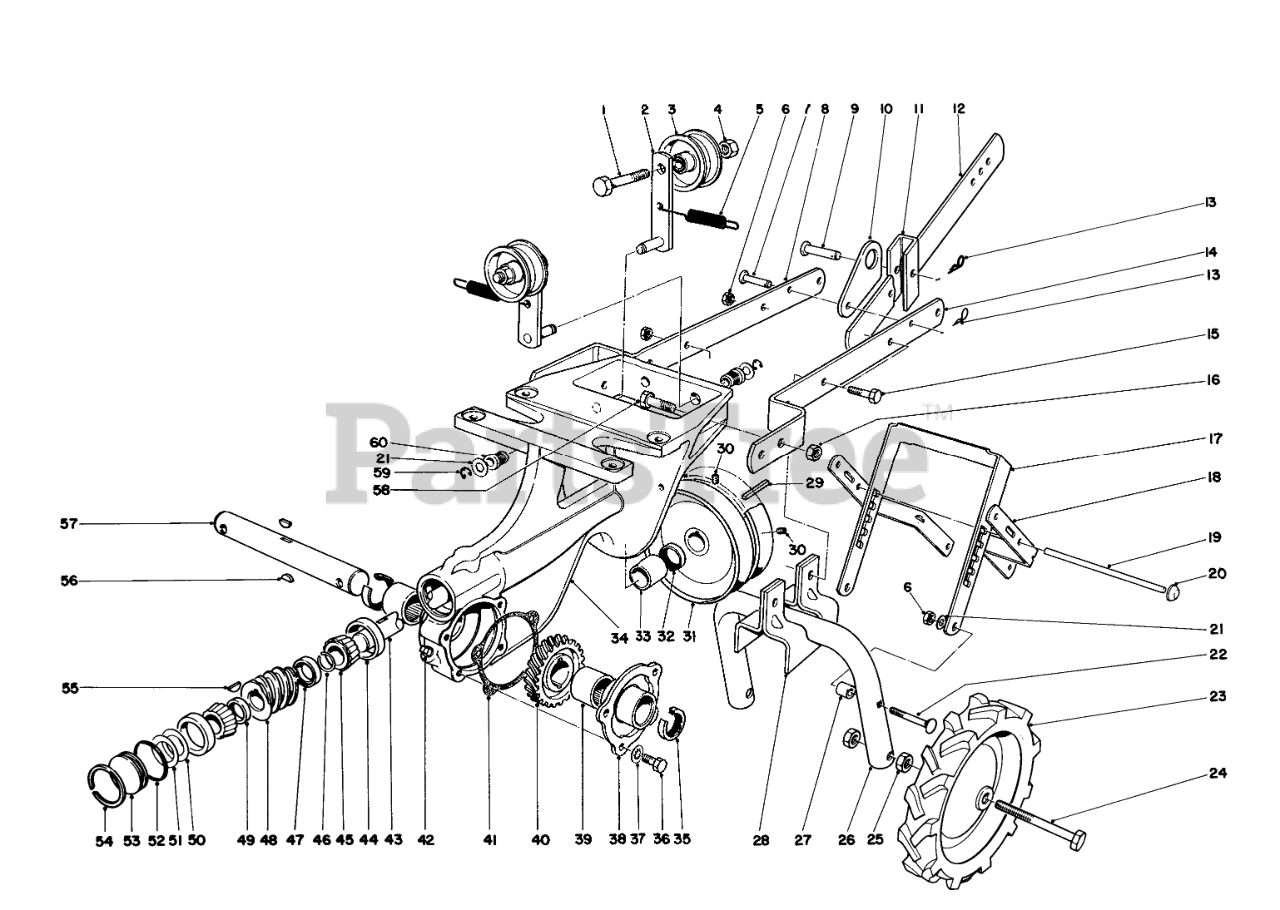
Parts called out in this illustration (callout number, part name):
1	SCREW-HH
2	Idler Arm
3	PULLEY IDLER
4	NUT-LOCK, CONE
5	TENSION SPRING
6	NUT-LOCK, CONE
7	PIN-CLEVIS
8	Drawbar R.H.
9	CLEVIS
10	Latch-Depth Gauge
11	DEPTH GUAGE BRKT
12	Depth Gauge
13	PIN-COTTER
14	Drawbar L.H.
15	SCREW-HH
16	NUT-KEPS
17	Lever Wheel Adjustment
18	HANDLE SUPPORT
19	Shaft-Wheel Adjustment
20	PUSH ON
21	WASHER-PLAIN
22	BOLT-CARR
23	Wheel
24	Wheel Bolt
25	NUT-HEX
26	Axle Yoke
27	Spacer
28	Saddle Yoke
29	KEY-SQUARE
30	SCREW-SET
31	WORM SHAFT PULLEY
32	SEAL-OIL
33	BUSHING
34	Chassis
35	SEAL-OIL
36	1/4-20 X 5/8 CAPSCREW
37	WASHER-LOCK
38	Cover
39	Needle Bearing
40	WORM WHEEL
41	GASKET
42	PLUG-PIPE, SQH
43	WORM SHAFT
44	BEARING-ROLLER, CUP
45	BEARING-CONE
46	RETAINER RING
47	Spacer Rear
48	WORM GEAR
49	SPACER
52	O-RING
54	INTRNL RETAINING RING
55	KEY-WOODRUFF
56	KEY-WOODRUFF
57	WORM WHEEL SHAFT
58	SCREW-HH
59	RING-RETAINING, EXT
60	IDLER BRG
